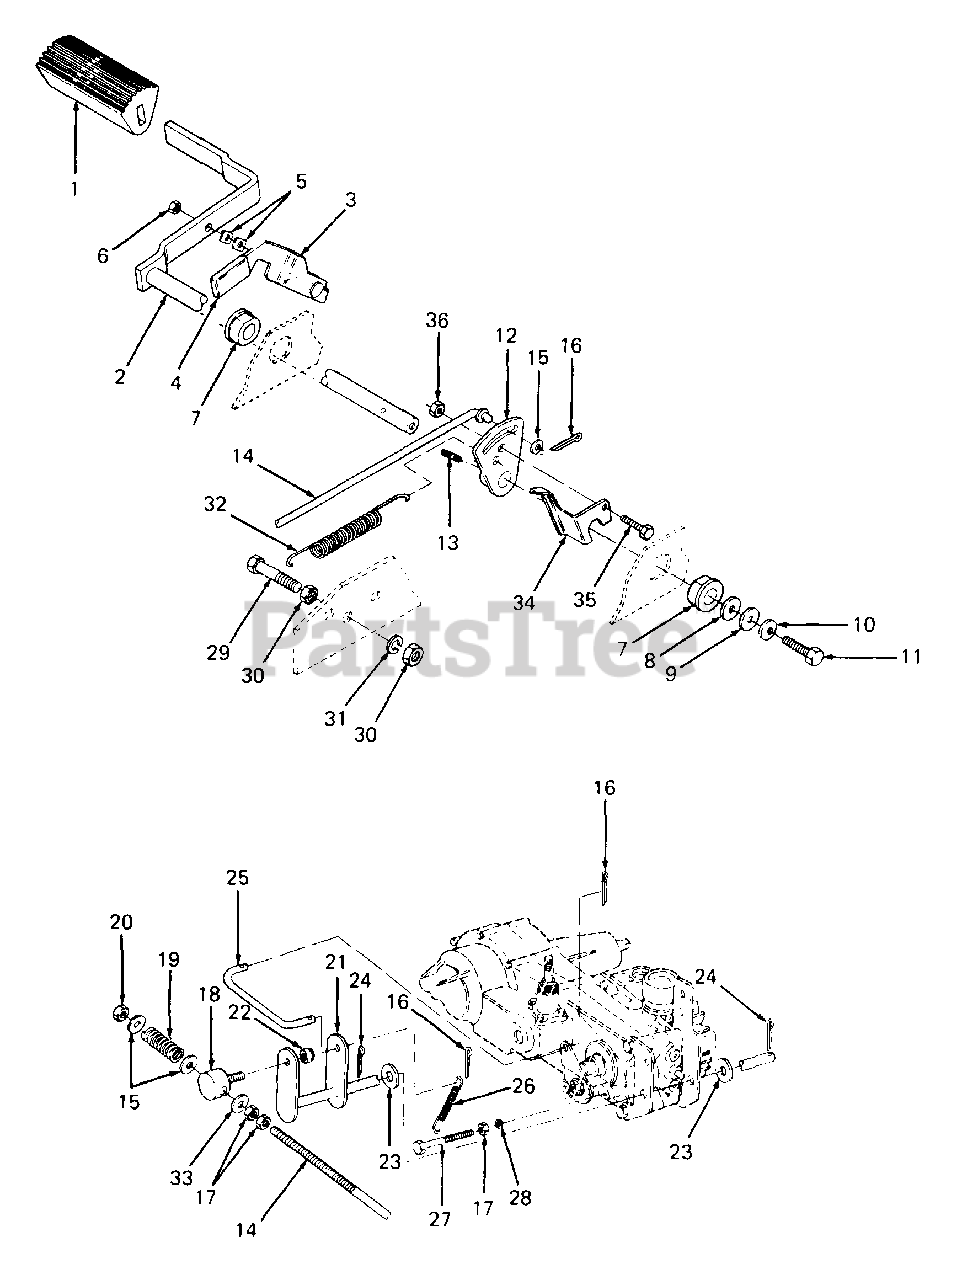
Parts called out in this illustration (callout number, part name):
1	Pad, Foot
5	Washer, Wave
6	Nut, Hex Insert Lock, 1/4-20
7	Bearing, Flange
8	Washer, Flat, .635 X 1.12 X .090 Thk
9	Washer, Flat, .26 X .93 X .120 Thk
10	Washer, Bell, .265 X .75 X .062 Thk
11	Screw, Hex Cap, 1/4-20 X .75 Lg GR5
12	Cam, Brake
13	Pin, Spiral Spring, 3/16 Dia X 1.5 Lg
14	Rod, Brake
15	Washer, Flat, .281 X .73 X .063 Thk
16	Pin, Cotter, 3/32 X .75 Lg
17	Nut, Hex Jam, 1/4-20
19	Spring, Compression, .58 OD X 2.00 Lg
20	Nut, Hex Center Lock, 1/4-20
21	Shaft, Brake
22	Nut, Hex Insert Lock, 5/16-18
23	Washer, Flat, .510 X 1.0 X .060 Thk
24	Pin, Cotter, 1/8 Dia X 1.0 Lg
25	Link, Brake
26	Spring, Extension
27	Screw, Hex Patch, 1/4-20 X 1.5 Lg GR5
28	Washer, Lock, 1/4
29	Screw, Hex Cap, 3/8-16 X 3.0 Lg
30	Nut, Hex, 3/8-16 GR5
31	Washer, Lock, 3/8
32	Spring, Extension, .50 OD X 3.97 Lg
33	Washer, Flat, .281 X .50 OD X .063 Thk
36	Nut, Hex Patch Lock, 1/4-20
